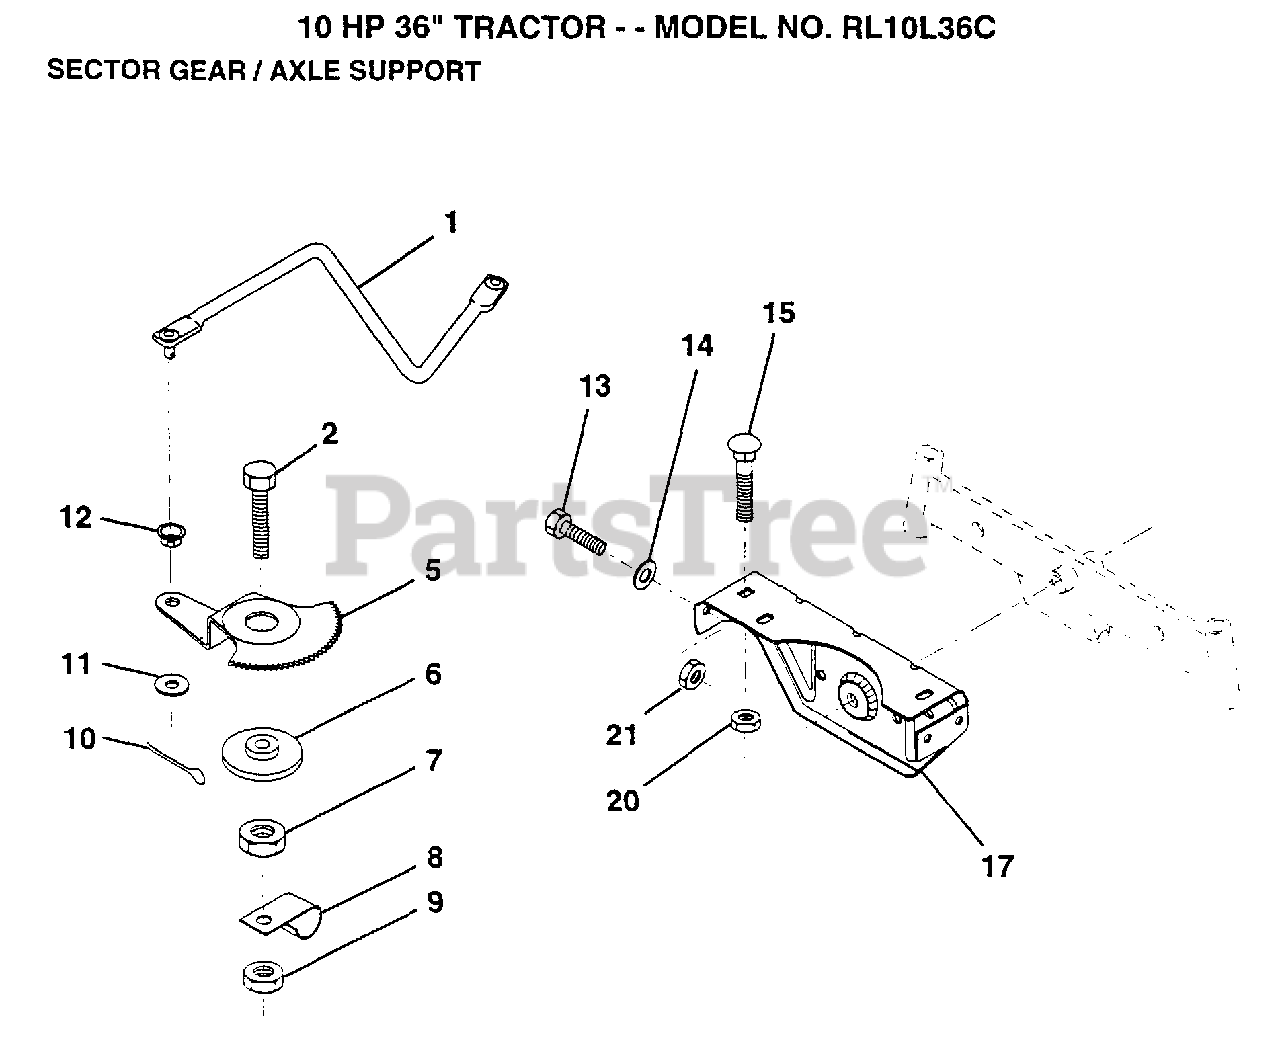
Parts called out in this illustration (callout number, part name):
1	DRAG LINK
2	"BOLT,HEX"
5	GEAR SECTOR
6	BUSHING
7	NUT
8	CLIP INSULATOR
9	NUT LTV
10	COTTER PIN
11	WASHER
12	BUSHING.DRAGLINK
13	BOLT
14	WASHER
15	BOLT
17	SUPT AXLE FRONT
20	NUT
21	NUT
